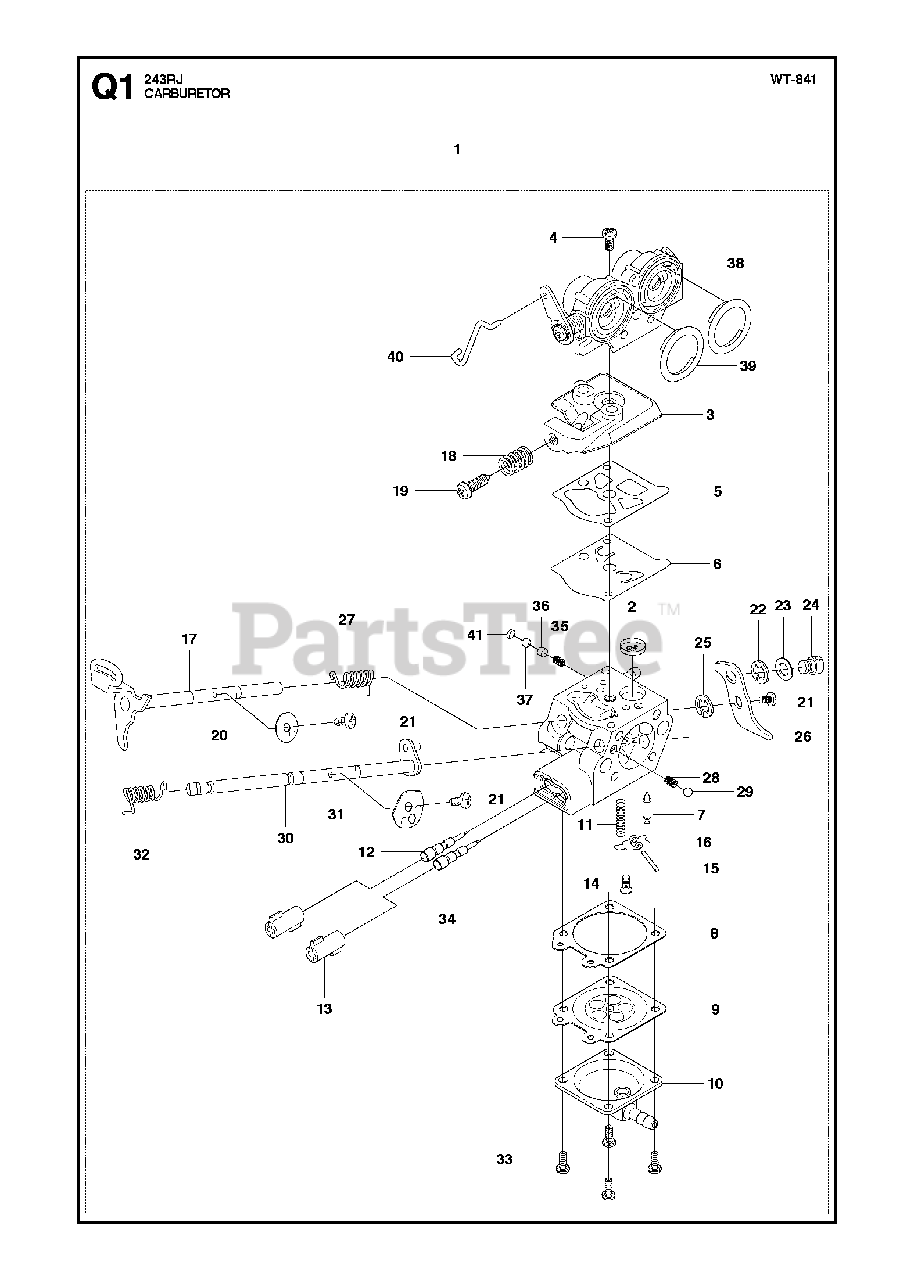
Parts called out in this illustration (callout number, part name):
2	SCREEN
3	COVER
4	SCREW
5	GASKET
7	VALVE INLET
9	DIAPHRAGM
10	COVER
11	SPRING
12	NEEDLE
13	CAP
14	SCREW
15	PIN
16	LEVER
17	SHAFT
18	SPRING
19	SCREW
22	RING
23	WASHER
24	SWIVEL
25	E-RING
26	LEVER, THROTTLE
27	SPRING RETURN
29	BALL
30	SHAFT, CHOKE
32	Spring
33	SCREW ASSY
34	NEEDLE
35	SPRING
36	PISTON
37	BALL
